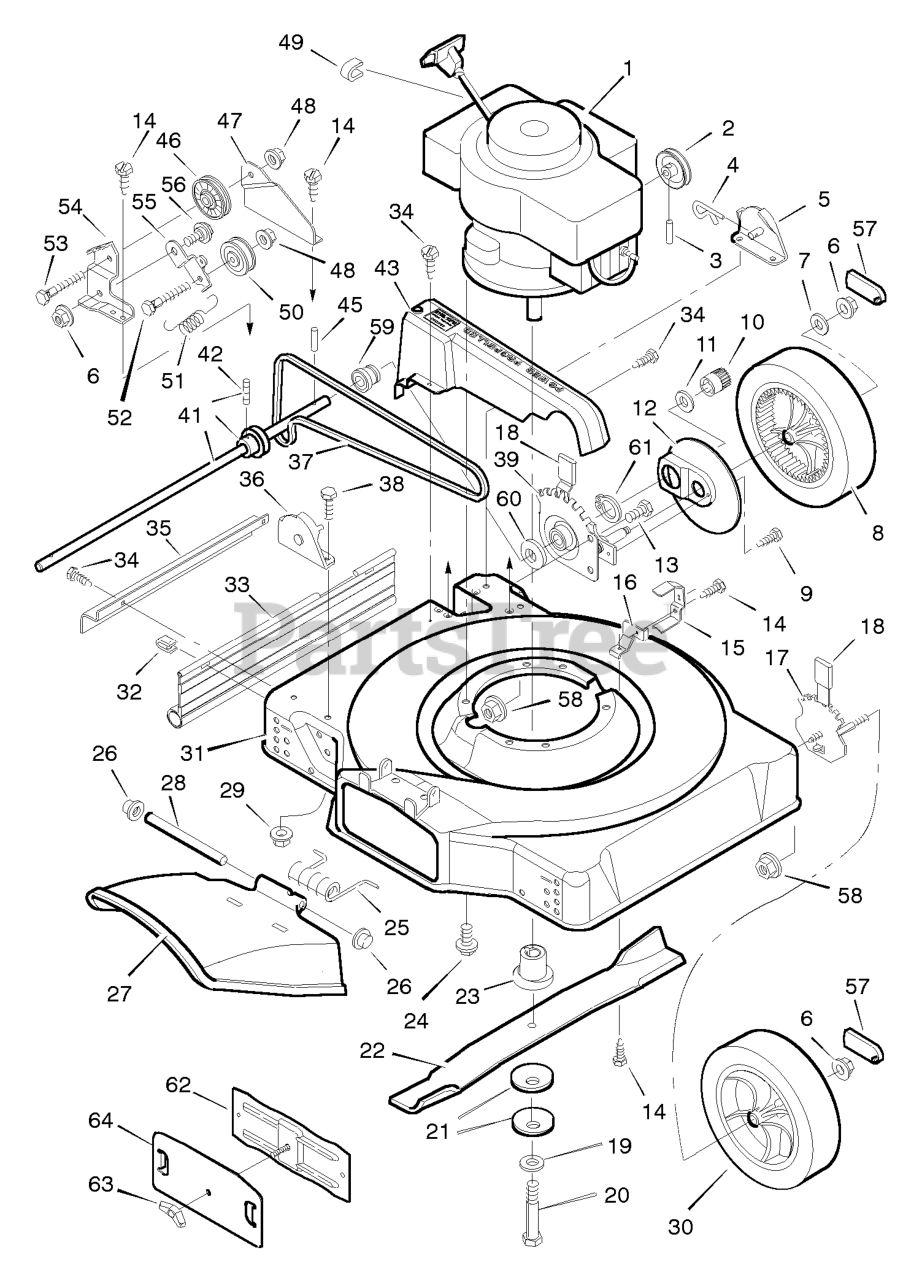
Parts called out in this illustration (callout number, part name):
1	Engine *
3	Pin, Spring
4	Pin, Hair
5	Bracket, Left Handle
6	Nut
7	Washer
8	Wheel, Drive
10	Gear, Right Pinion
12	Cover, Dust
13	Bolt, Hex
15	Guide, Belt
16	Belt Guide, Briggs
17	Height Adjuster, Front
21	Washer, Belleville
23	Adapter, Blade
24	Bolt, Engine
25	Spring, Torsion
26	Push On Cap
27	Deflector, Chute
29	Nut
30	WHEEL & TIRE ASSEMBLY, White, 8"
31	Housing
32	Retainer
33	Deflector, Rear
35	Guard, Axle
36	Bracket, Right Handle
37	Belt, Briggs & Stratton
39	Height Adjuster, Left
41	Axle, Pulley & Setscrew
42	Setscrew
43	Belt Guard, Briggs
45	Pin, Drive
46	Pulley, Idler
47	Support, Idler
48	Nut
49	Stop, Rope
50	Pulley, Idler
51	Spring, Extension
52	Bolt, Hex
53	Bolt, Hex
54	Bracket, Idler
55	Arm, Idler
56	Bolt, Shoulder
57	Cap, Hub
58	Nut, Flange
59	Bearing and Retainer
60	Washer, Belleville
61	Retainer Ring
63	Wingnut
